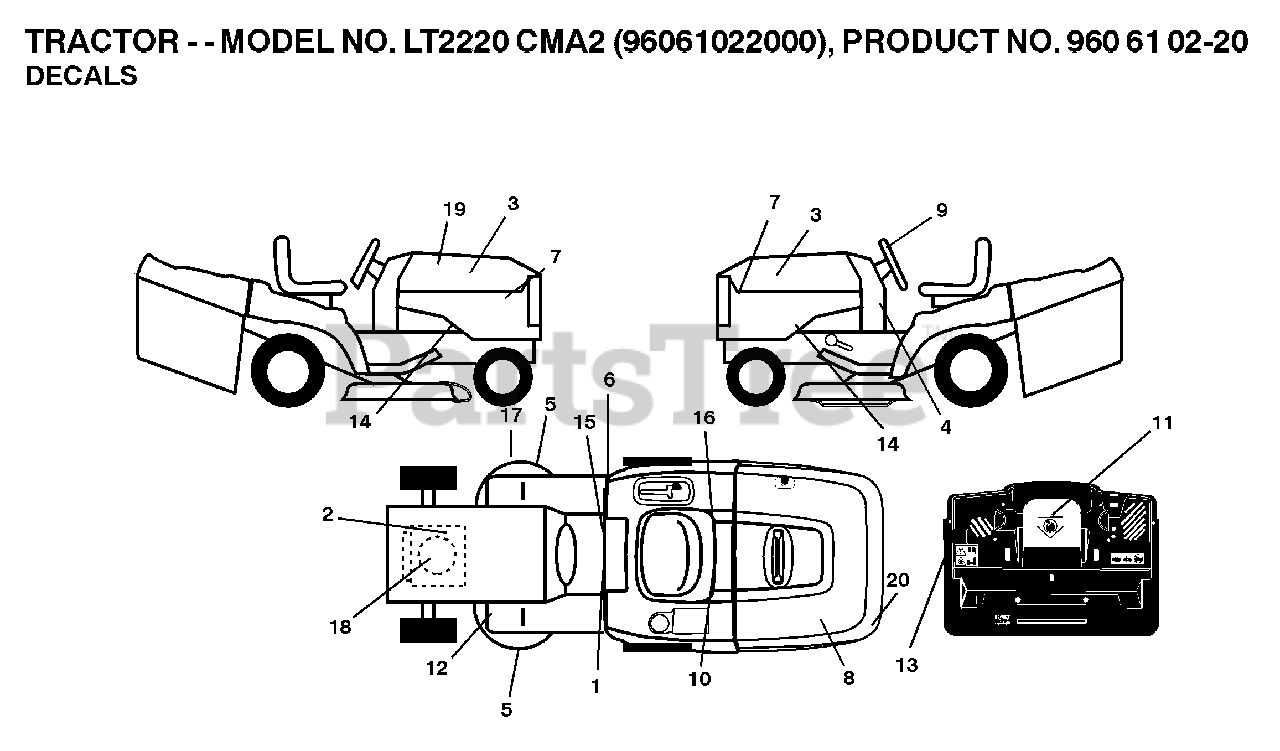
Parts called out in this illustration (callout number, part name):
6	DECAL.80 DBA.AUSTRALIA
10	DECAL BTRY SYMBOLS
11	DECAL.INTERNATIONL.CUTFINGER
15	DECAL PARK BRAKE
16	DECAL.BYPASS.FENDER.CRD.LT.YT
